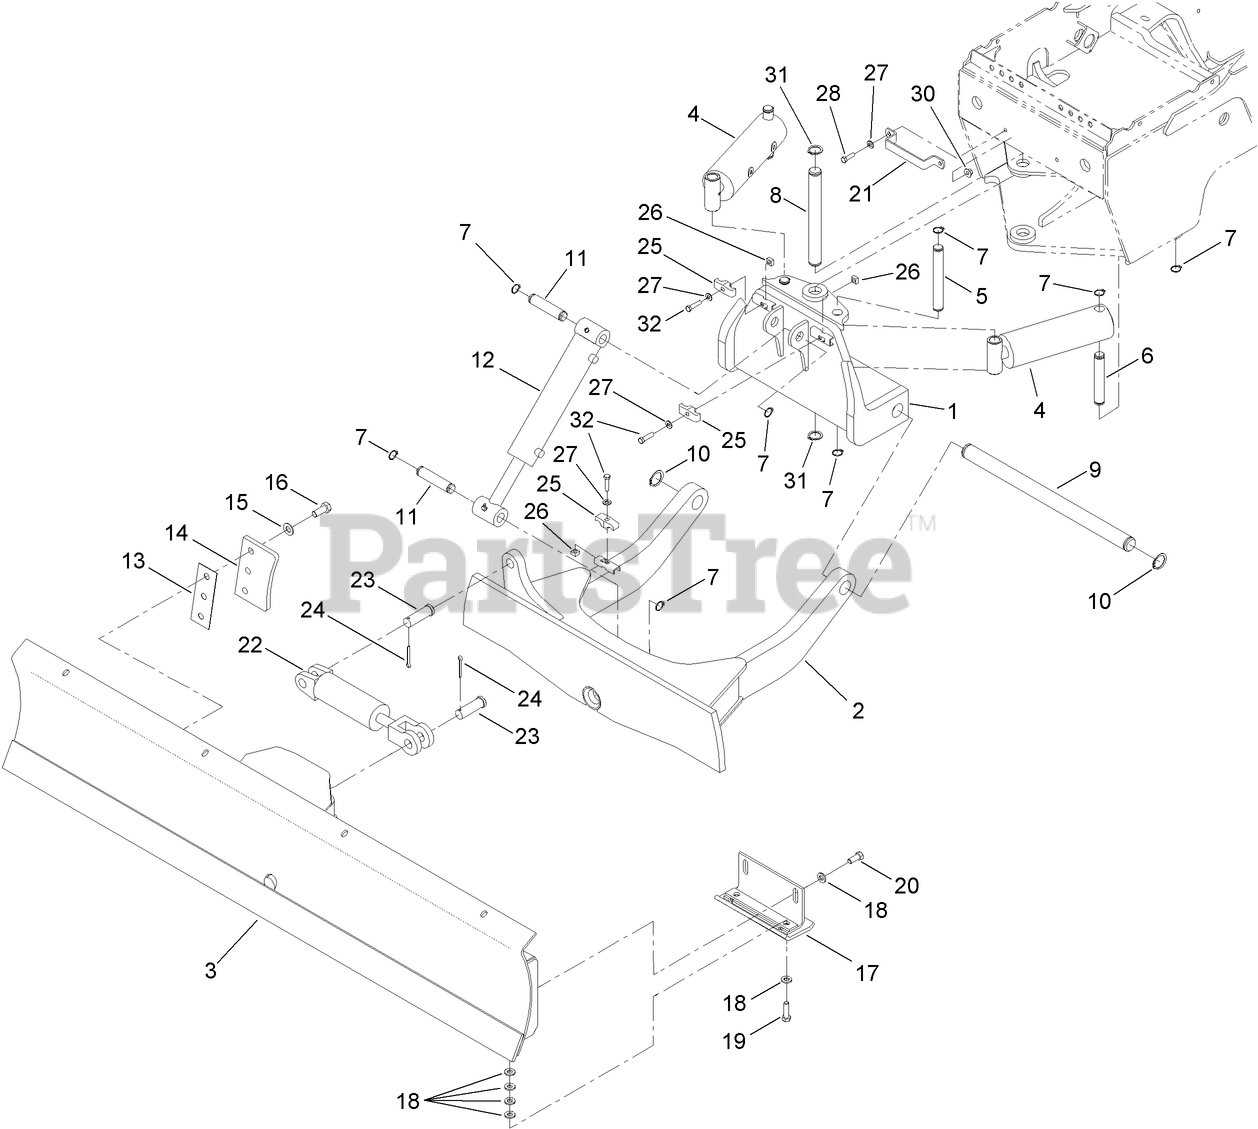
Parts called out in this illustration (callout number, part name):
1	PIVOT-BACKFILL
4	HYD CYLINDER ASM
5	PIN-LINK
6	PIN-LINK
7	RING-RETAINING
8	PIN-Pivot
9	PIN-Frame
11	PIN-CYLINDER
12	HYD CYLINDER ASM
13	SHIM-RETAINER
14	RETAINER-BLADE
15	WASHER-FLAT
16	SCREW-HH
17	SHOE-SKID
18	WASHER-FLAT
19	SCREW-HH
20	SCREW-HH
21	BRACKET-HOSE
22	HYD CYLINDER ASM
23	PIN-HEADED
24	PIN-COTTER
26	NUT-SQUARE
27	WASHER-FLAT
28	SCREW-HH
30	NUT-FLANGE
31	RING-RETAINING
32	SCREW-HH
